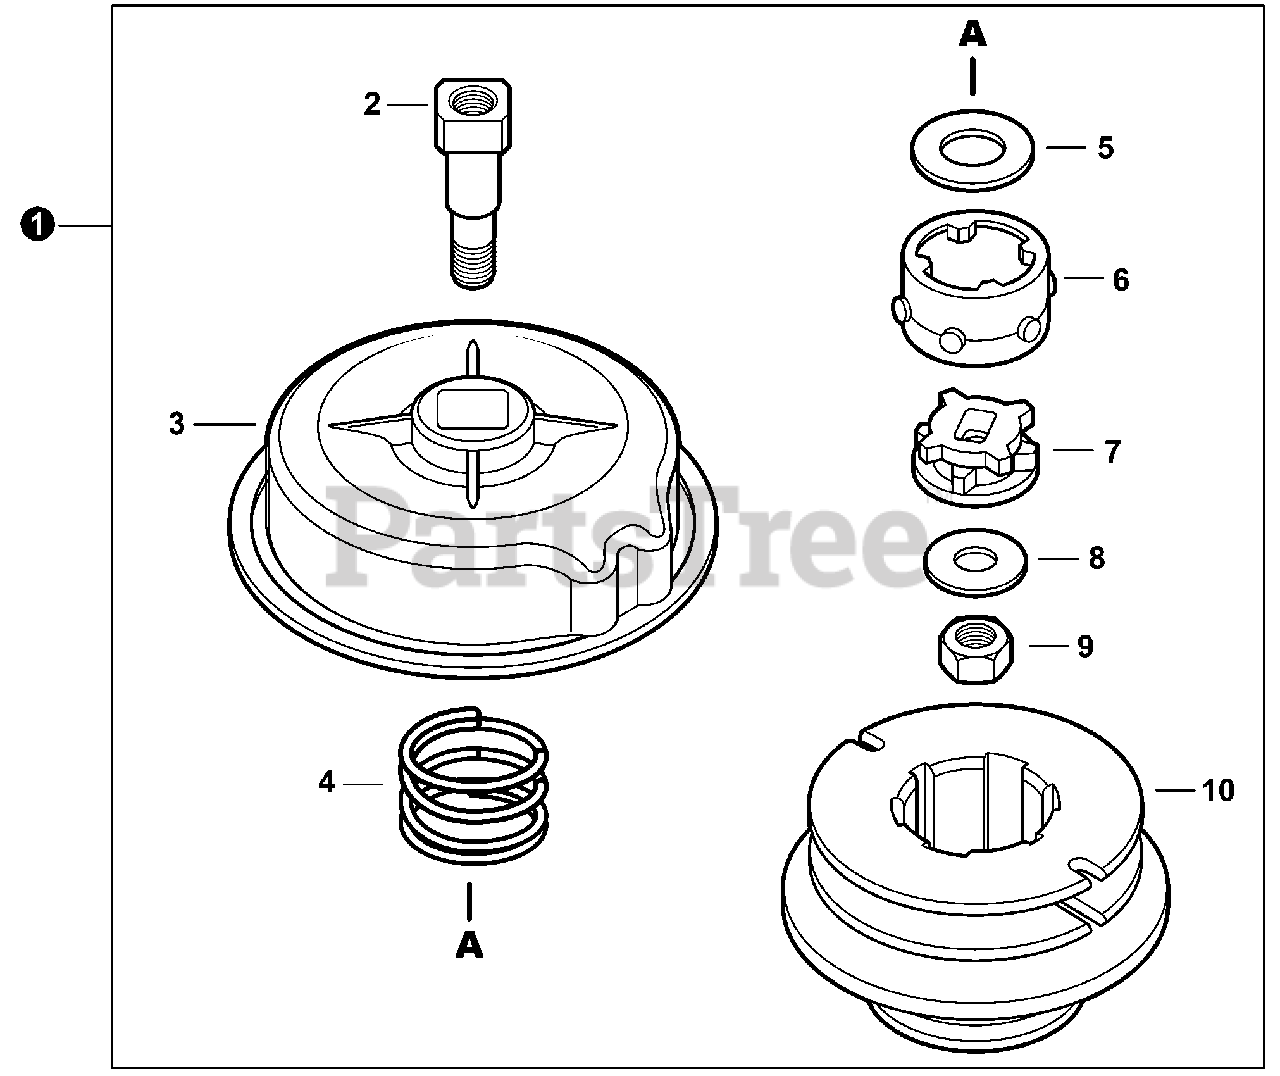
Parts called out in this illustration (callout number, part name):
1	ECHOMATIC PRO HEAD ASSEMBLY
2	BOLT, SHAFT - 10
3	HOUSING
6	DRIVER, OUTER
7	CAM, INNER
9	LOCKNUT
